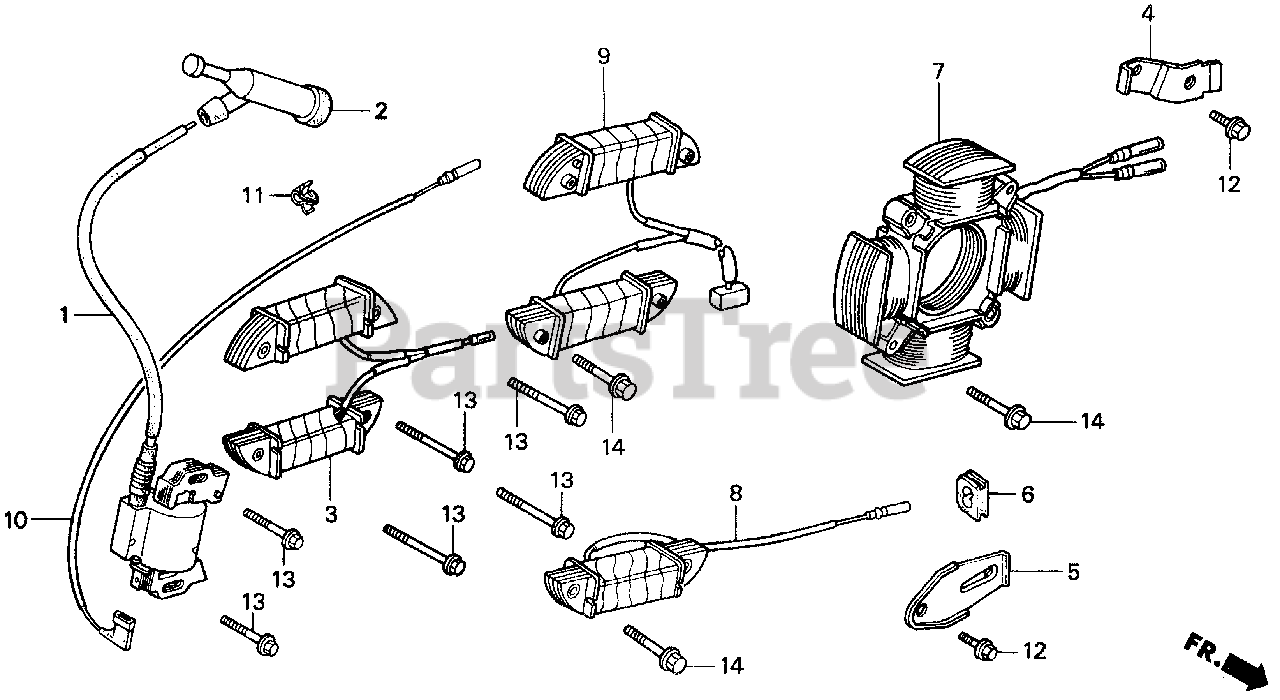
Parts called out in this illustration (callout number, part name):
1	COIL ASSY., IGNITION
2	CAP ASSY., NOISE SUPPRESSOR
4	CLAMP, WIRE
6	GROMMET, WIRE
7	COIL ASSY., CHARGE (12V-18A)
10	WIRE, STOP SWITCH (370MM)
12	BOLT, FLANGE (6X12) (CT200)
13	BOLT, FLANGE (6X28)
14	BOLT, FLANGE (6X32)
